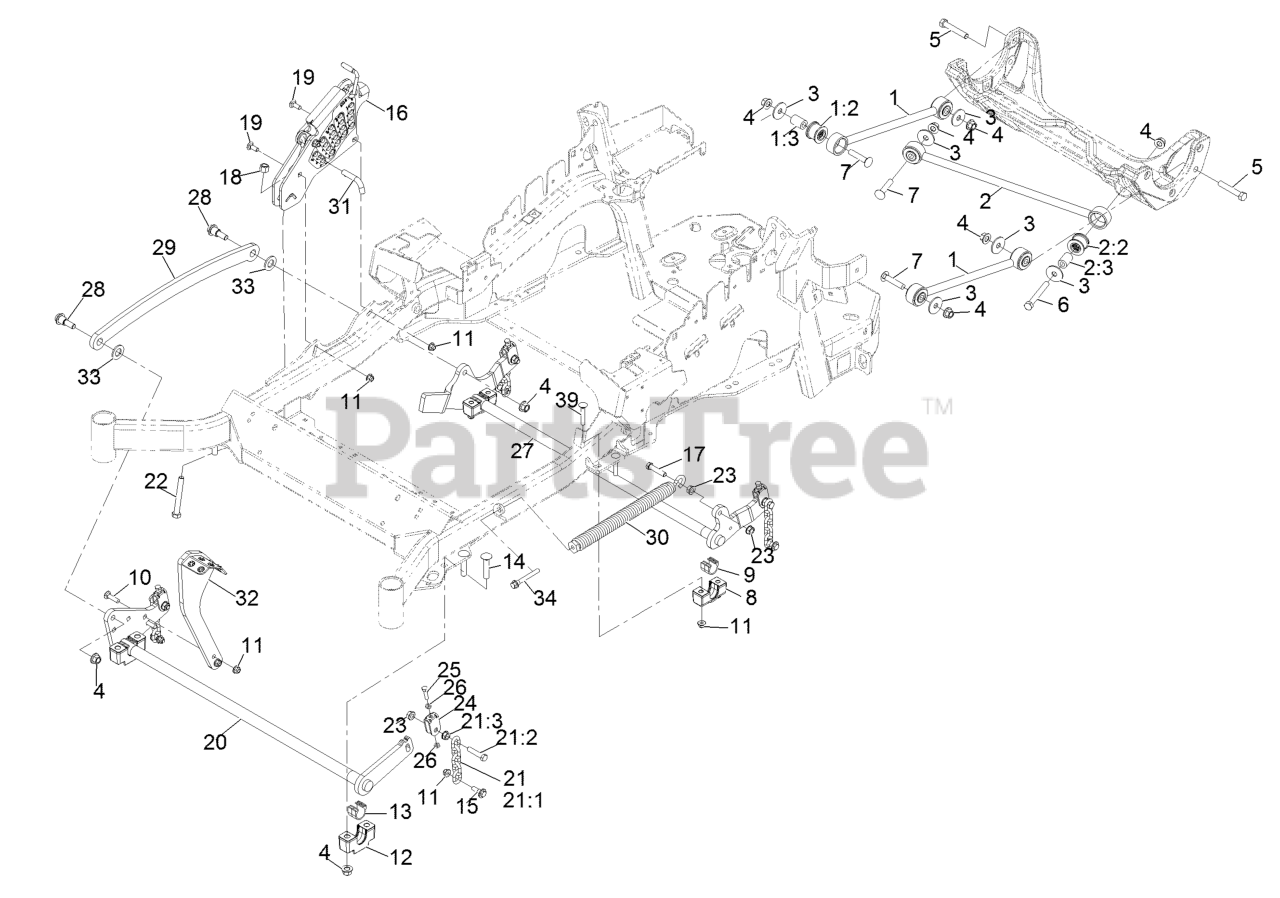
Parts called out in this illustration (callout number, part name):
1	DECK STRUT ASM
1:2	BUSHING-SUSPENSION, RUBBER
2	PANHARD ROD ASM
2:2	BUSHING-SUSPENSION, RUBBER
3	WASHER-THRUST
4	Nut-Lock 1/2-13
5	SCREW-HH
6	SCREW-HH
7	SCREW-CARR
8	SUPPORT-CROSS SHAFT, BEARING REAR
9	BEARING-CROSS SHAFT, REAR
10	SCREW-CARR
11	NUT-HF, NI
12	SUPPORT-CROSS SHAFT, BEARING
13	BEARING-CROSS SHAFT, FRON
14	Bolt-Carriage 1/2-13 X 2 1/2 Spl Neck
15	SCREW-SHOULDER, HHF
16	HOC ASM
17	SCREW-HH
18	NUT-LOCK, NI
19	BOLT-CARR
20	DECKLIFT-FRONT
21	DECK LIFT CHAIN ASM
21:1	CHAIN-LIFT, DECK
21:2	SCREW-HH
22	BOLT-TAP
24	YOKE-ADJUST, DECK
25	SCREW-HH
26	NUT-JAM
27	LIFT-DECK, REAR
28	SCREW-SHOULDER, HHF 1/2-13 X 1.12
29	LINK-LIFT, DECK
30	SPRING-EXTENSION
31	PIN-HOC
32	LEVER-FOOT
33	WASHER-FLAT
34	BOLT-SHOULDER
39	Bolt-Carriage 3/8-16 X 2 1/4
